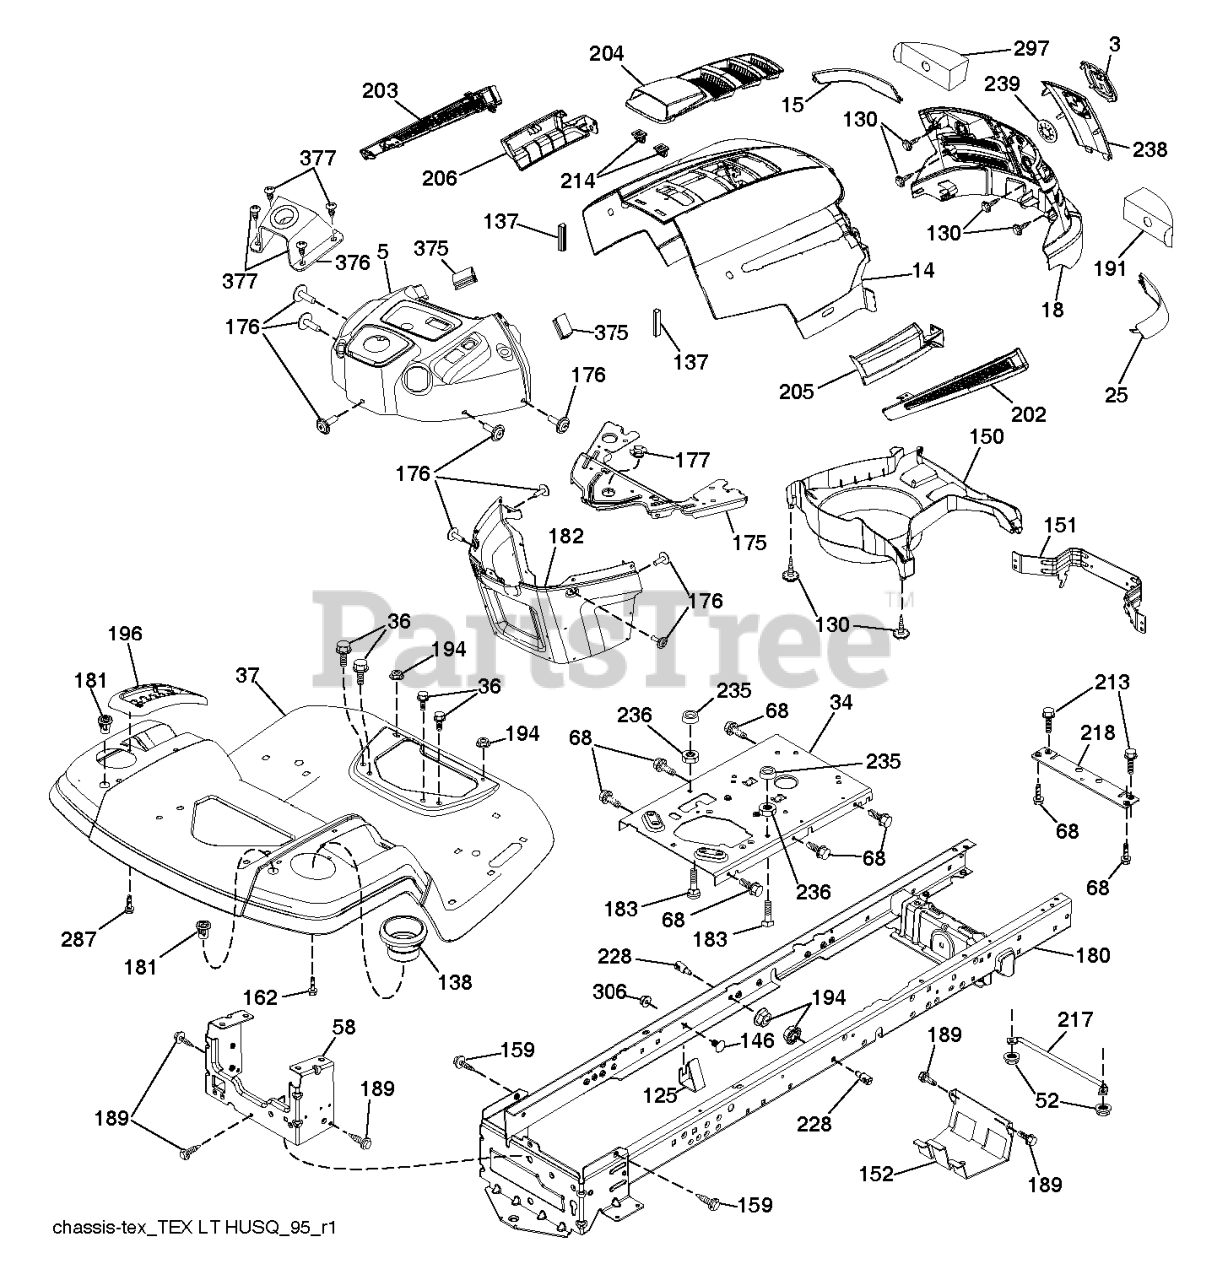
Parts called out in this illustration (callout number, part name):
3	LOGO.HUSQ.GT.LT.CROWN.H
5	DASH.UPPER.HUS.LT.CABLE.CLUTCH
14	HOOD.HUSQVARNA.LT.ORANGE
15	LENS.HUSQVARNA LT.RH
18	GRILLE.SVC.HUSQVARNA.GREY
25	LENS.HUSQVARNA LT.RH
34	PLATE.ENGINE.WELDED.CHASSIS
36	SCREW 5/16"
37	FENDER.TLT.PDL.CNTRL.W/CPH.ORG
58	DRAWBAR UPPER 2PC SMALL FENDER
125	CLIP.FUEL.LINE
137	BUMPER DASH
138	HOLDER.CUP.LT.GREY
146	BOLT.RDHD.SHT.SQNK.3/8-16X5/8
151	BRACKET PIVOT
152	SHIELD.BROWNING.W/TEX
159	SCREW, 3/8-16X3/4
175	CROSSMEMBER
176	SCREW.#10-24X5/8.RN.QU
177	BUSHING STEERING
180	CHASS.WLDMNT.TL.12GA/2P.48/54
181	BUSHING.MNT.FEND.CRGO.TEX.49
182	DASH.LOWER.PREDATOR LT
189	SCREW
191	INSERT.REFLECTIVE.RH.
196	DECKLFT.CONSOL FULL ASSM GREY
202	VENT.SIDE.HUSQVARNA.LT.RT
203	VENT.SIDE.HUSQVARNA.LT.LFT
204	SUBASM.TOP.VENT.HUSQ.LT
205	SKIRT.SIDE.HUSQVARNA.LT.RT
206	SKIRT.SIDE.HUSQVARNA.LT.LEFT
213	SCREW HEXAGON HEAD SCREW 5/16-
214	CLIP.RETAINER.TINNER.
217	ROD.PIVOT.HOOD
218	X-PIECE.HOOD.STOP.NON/
228	STUD.FASTNER.W/ANTI-ROTATE
236	NUT.CENTERLOCK.5/16-
238	TRIM.HUSQ LT.668
287	SCREW 1/4X20
297	INSERT REFLECTIVE
306	NUT LOCK FLG 3/8-16 UNC
375	BUMPER CLIP-ON. DASH 1"
376	MOUNT.ASM.HUSLT.UPPER.STRNG
377	SCREW 10 X 1/2 ZN PL PHIL PAN
